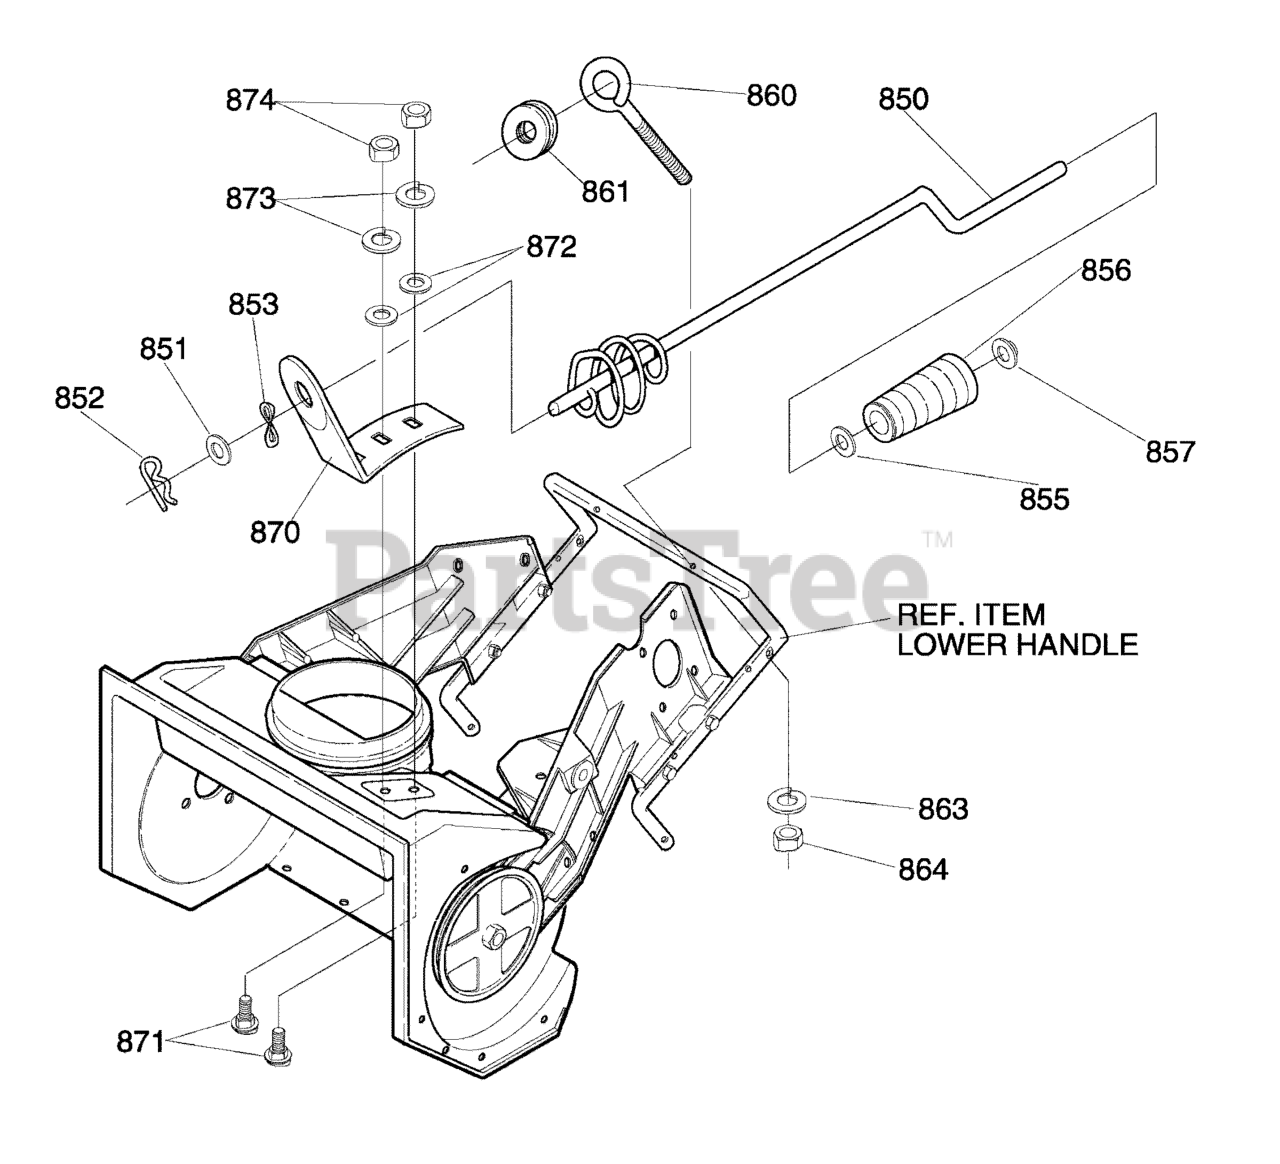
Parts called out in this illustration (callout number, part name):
850	ROD, ASSY UPPER CHUTE CONTROL
851	WASHER, FLAT .406X.81X.066
852	PIN, COTTER
853	WASHER, CURVED SPRING
855	WASHER, FLAT .406X.81X.066
856	KNOB, SLEEVE
857	NUT, PUSH
860	BOLT, EYE 3/8-16X2.00
861	GROMMET, EYE BOLT
864	NUT, HEX JAM 3/8-16
870	BRACKET, CHUTE ROTATE
871	BOLT, CARRIAGE 5/16-18X.75
872	WASHER, FLAT .349X.69X.066
873	WASHER .328X.60X.09
874	NUT, HEX 5/16-18
